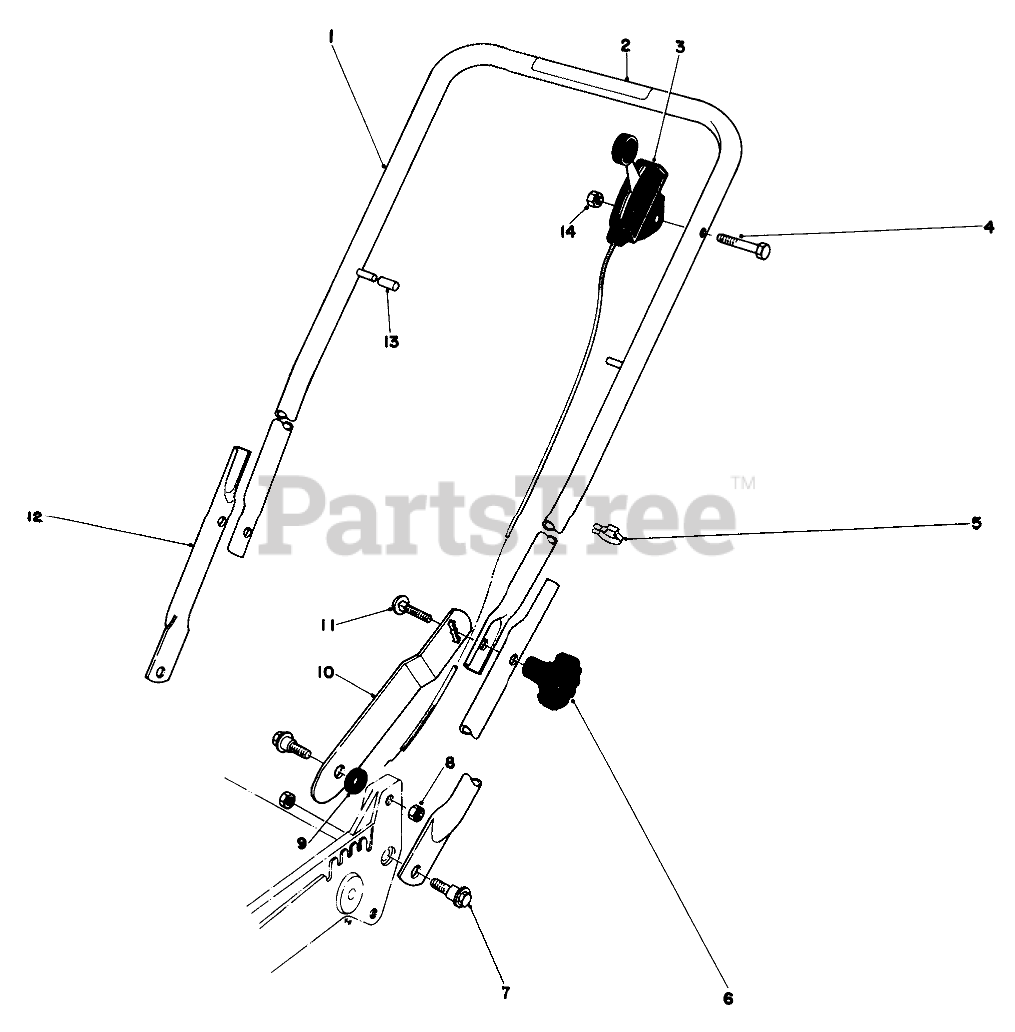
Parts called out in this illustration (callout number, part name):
1	Upper Handle
2	Decal
3	Throttle Control
4	SCREW-HH
5	BOWDEN CLIP
7	Screw
8	Nut
9	SPACER
10	Handle Latch L.H.
11	SCREW-CARR
12	LOWER HANDLE
13	CAP-VINYL
14	NUT-LOCK
